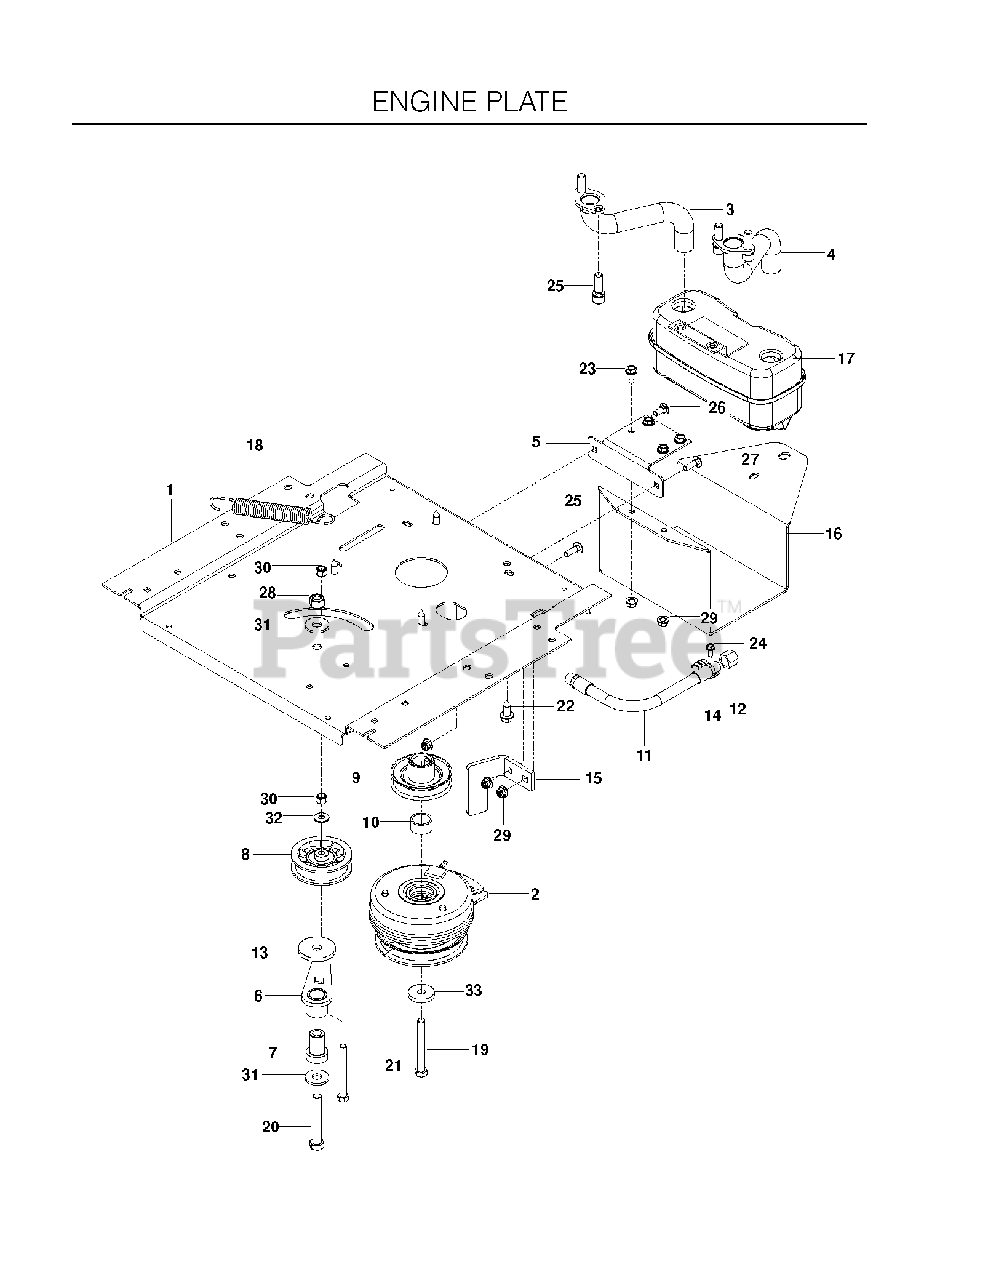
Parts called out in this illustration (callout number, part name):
1	PLATE, ENGINE BLK
2	CLUTCH, 105 FT-LBS
3	RP.PIPE-EXHAUST LH
4	RP.PIPE-EXHAUST RH
5	BRACKET, MUFFLER, BLACK
6	IDLER ARM WELDMENT
7	IDLER SPINDLE
8	PULLEY, IDLER RAKE & ZTR
9	RP PULLEY, ENGINE
10	HUB PULLEY SPACER
11	OIL DRAIN HOSE
13	HEAVY WASHER
15	STOP, CLUTCH, BLACK
16	GUARD, MUFFLER, BLACK
17	MUFFLER ASM TWIN
18	SPRING, DECK DRIVE
19	HCS 7/16-20 X 2.5 GR8
20	HCS 1/2C X 3 1/4
21	HCS 3/8-16X3 1/2 GR5
22	HHFS 3/8-16 X 1.0 THD FORMING
23	BOLT 5/16-18 X 3/4
24	SCREW 1/4 X 5/8
25	SCREW.SOCKET.HEAD.5/16-18
26	BOLT 5/16C X 3/4" CARRIAGE
27	RHSNB 5/16C X 1
28	RP NUT 1/2-13 HEX NYLOC ZD
29	5/16-18 NYLOC FLANGE NUT
30	NUT 3/8-16 NYLOC
31	WASH USS FLAT 1/2
32	WASHER 5/16 FLAT
33	CLUTCH, WASHER
